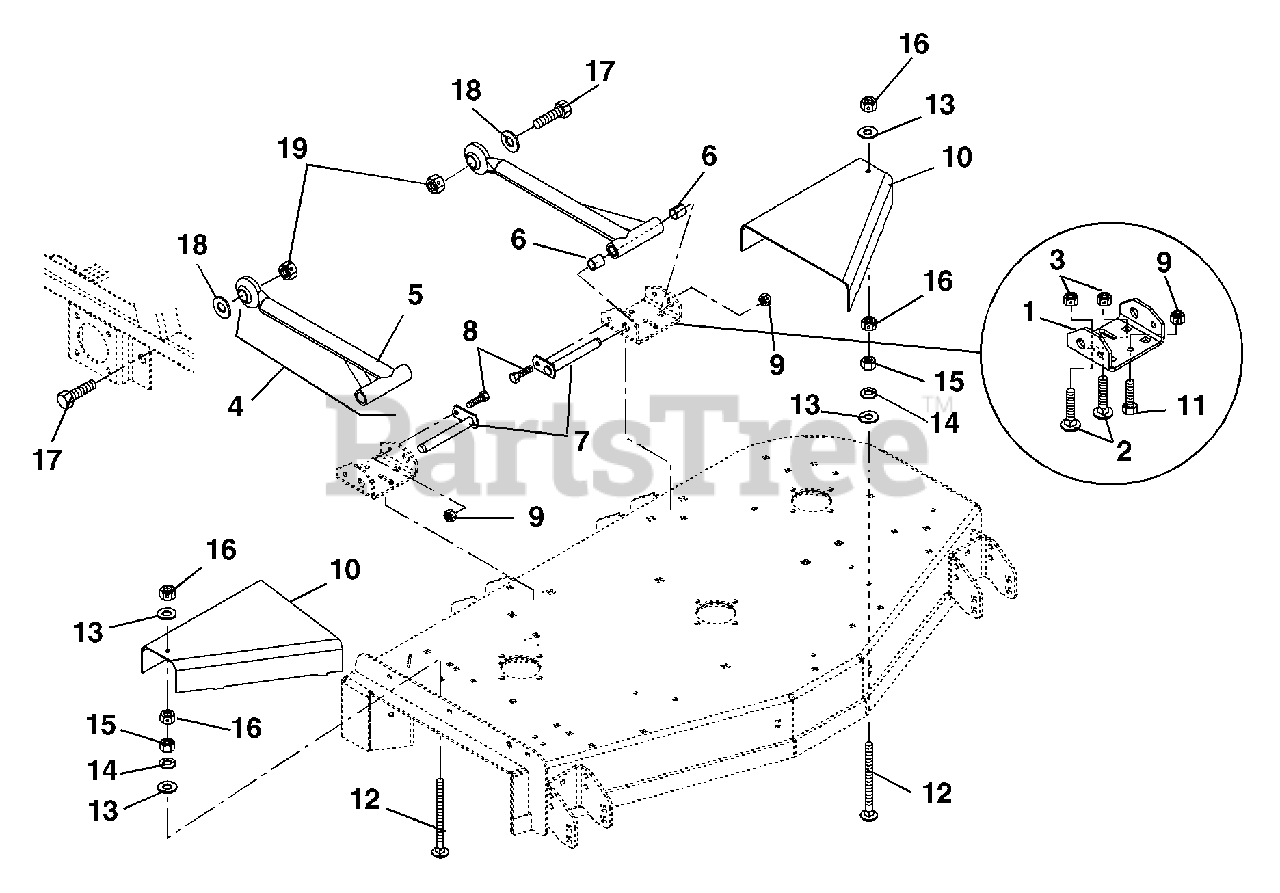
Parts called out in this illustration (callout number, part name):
1	BRACKET, MOWER MOUNT (REAR)
2	@BLT-RDHDSQNK .50-13X.75 G5YZ
3	NUT-LK-CTR-JAM .50-13 YWZC(ND)
4	ASSEMBLY, MOWER MOUNTING ARM
5	WMT, MOWER MTG ARM - BLACK
6	BRG, .750 X .875 X 1.000
7	WELDMENT, MOWER MTG. PIN
8	@BLT-HEX .38-16X1.00 GR5 YWZC
9	@NUT-LK-TOP-FLG .38-16 YWZC
10	GUARD, PULLEY LH
11	@BLT-RDHDSQNK .38-16X.75 G5YZ
12	BLT-RDHDSQNKFTH.312-18X3.50YWZ
13	@WSHR-FL-STL.344X.688X.065YWZC
14	@WSHR-LK .31X.078 REG YWZC
15	@NUT-HEX .31-18 YWZC
16	@NUT-LK-CTR .31-18 YWZC
17	BLT-HEX .875-9X2.75 GR5 YWZC
18	WSHR-FL-STL .890X1.500X.1196YZ
19	NUT-LK-CTR .875-9 YWZC
